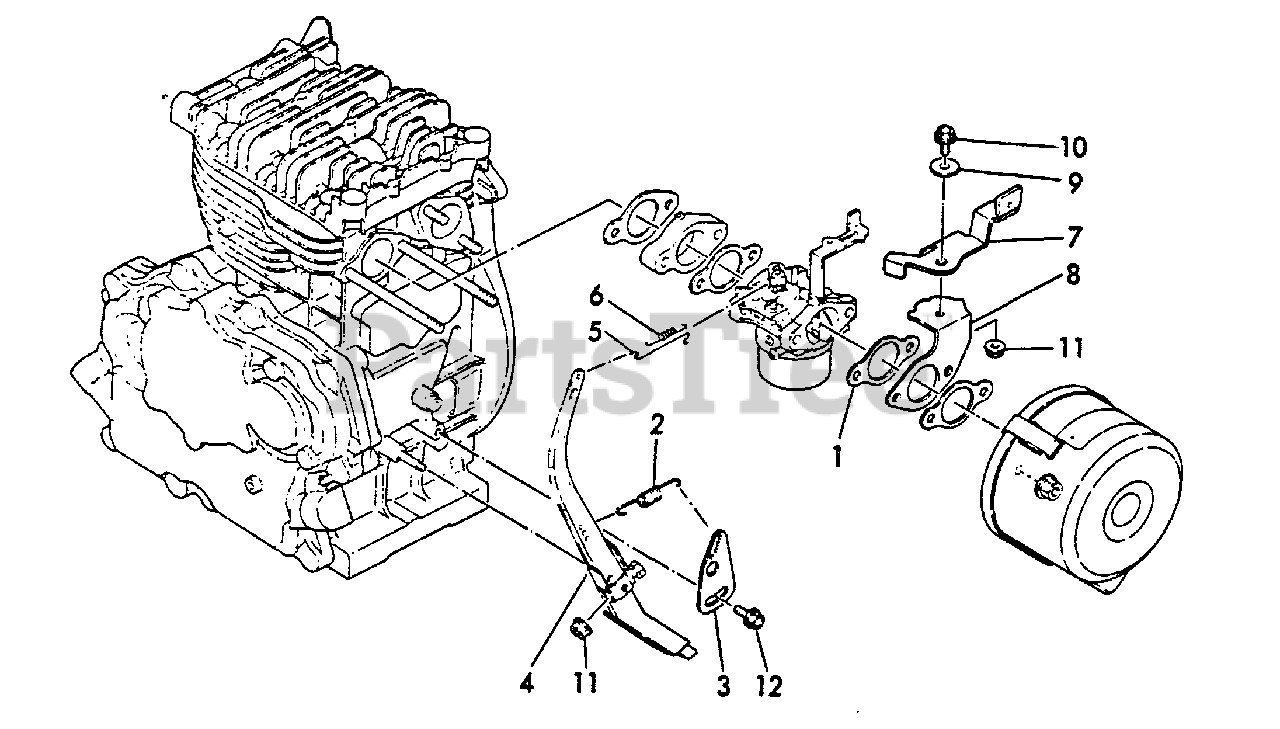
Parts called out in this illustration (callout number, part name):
1	GASKET, INTAKE
2	SPRING, REGULATOR
3	HANDLE, REGULATOR
4	LEVER, GOVERNOR
5	LINK, THROTTLE
6	SPRING, TENSION
7	LEVER ASSY
8	BRACKET, LEVER
9	COLLAR
10	BOLT - 6×12 -- PLATED
11	U-NUT M6
12	BOLT - 6×8 -- PLATED
